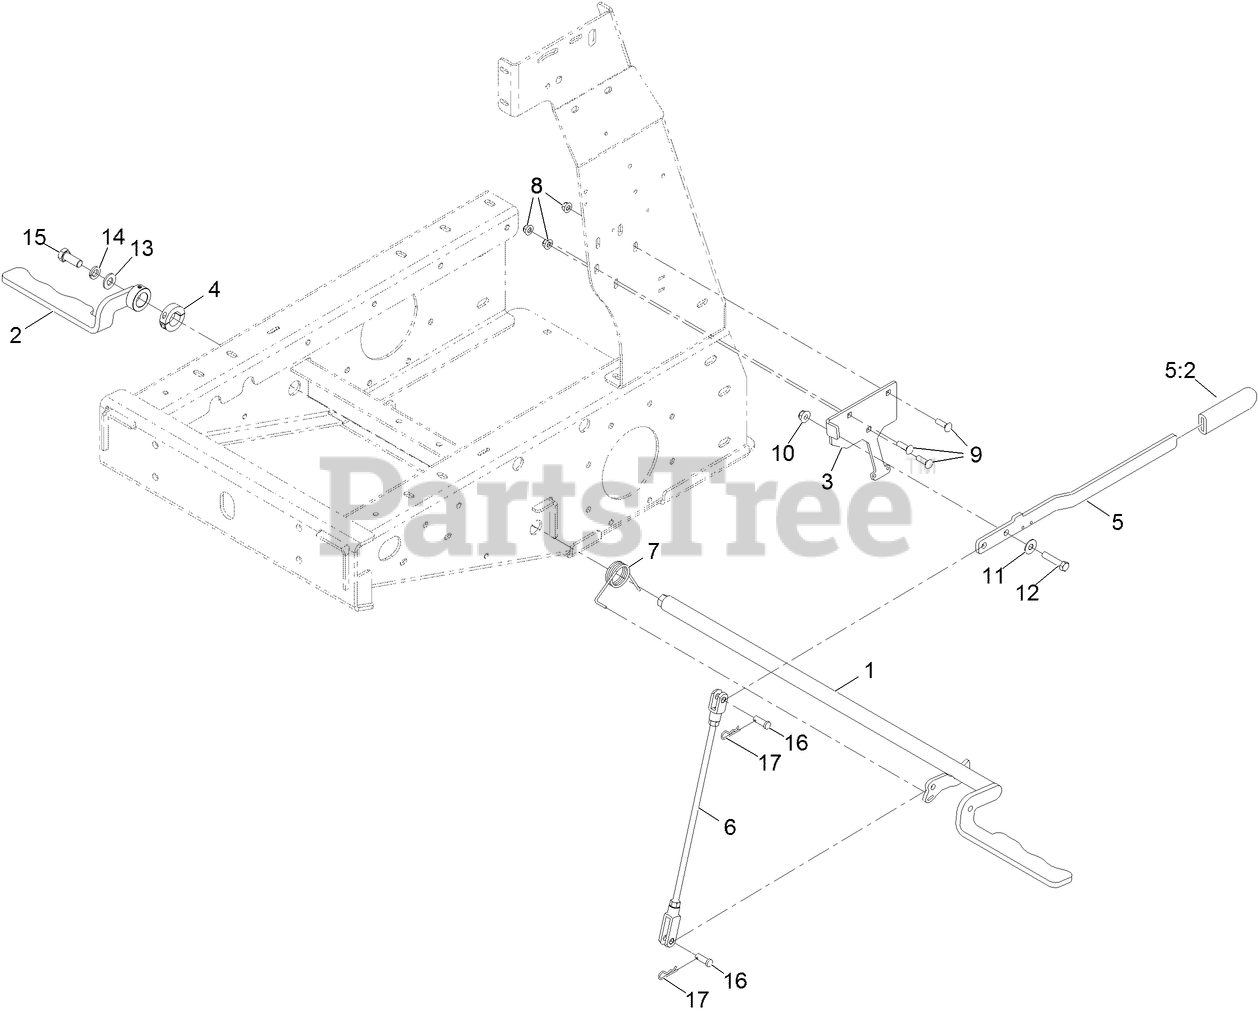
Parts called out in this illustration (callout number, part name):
1	Arm-Brake, Lt [black]
2	Arm-Brake, Rt [black]
3	BRACKET-HANDLE, BRAKE
4	COLLAR-LOCKING
5	ASM, Handle-Brake
5:2	GRIP-LEVER
6	ASM, Rod-Brake
7	SPRING-TORSION
8	Nut-Hex Flange
9	Bolt,Carriage,5/16-18X1,ST/ST 18-8
10	NUT-HF, NI
11	WASHER-FLAT
12	SCREW-HH
13	WASHER-FLAT
14	WASHER-LOCK
15	Screw ( .50-20Unfx1.25 Grade 8]
16	PIN-CLEVIS
17	Pin-Hair
